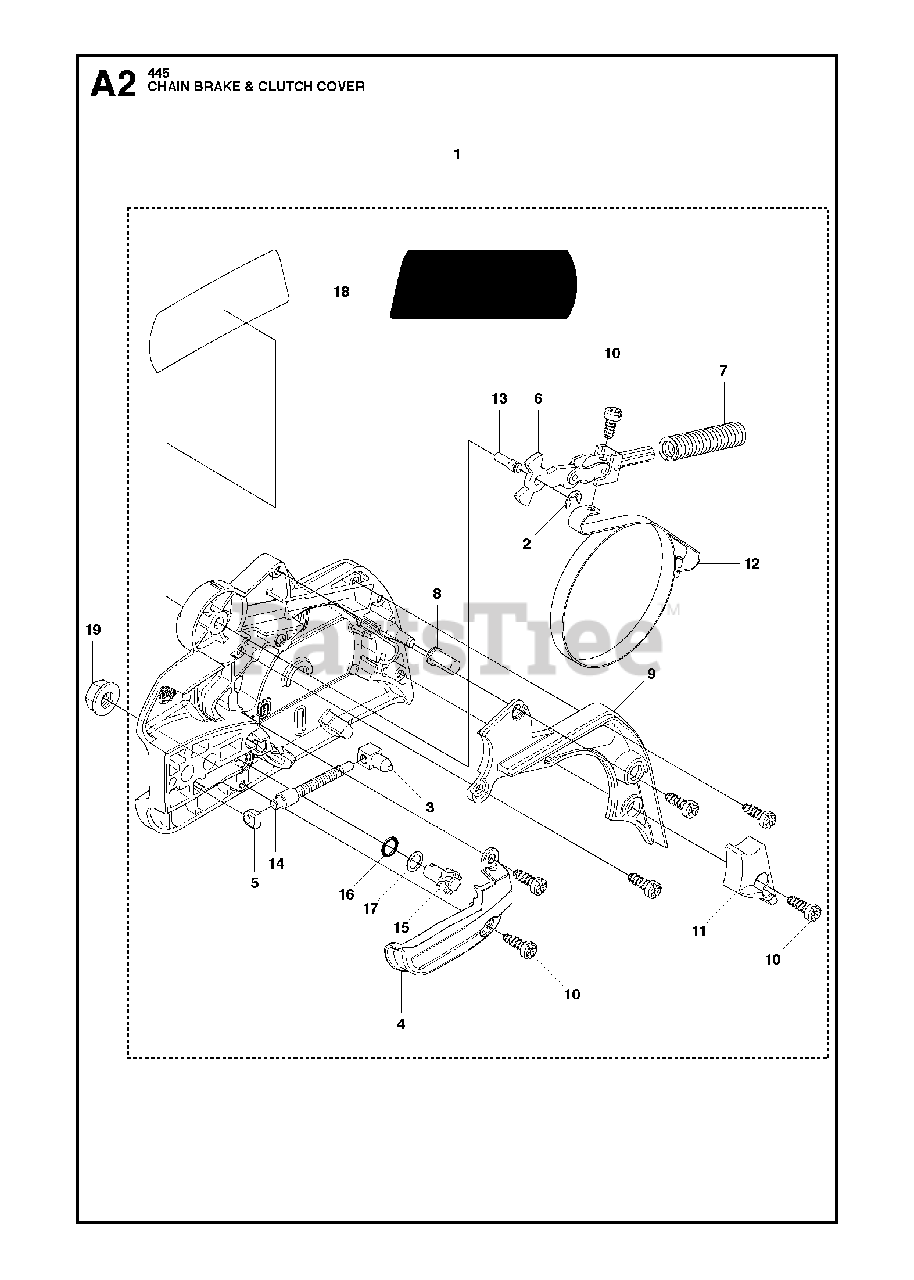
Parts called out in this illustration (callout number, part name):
1	CLUTCH COVER
2	E-RING 4
3	PAWL
4	CHAIN GUIDE
5	SLEEVE
6	JOINT
7	SPRING
8	SLEEVE
9	COVER, CHAIN BRAKE
10	SCREW
11	WEAR GUARD, CHAIN
12	BRAKE BAND
13	PIN
14	SCREW
15	WORM WHEEL
16	O-RING
17	WASHER
18	LABEL 400 SERIES
19	NUT M8 FLANGE
